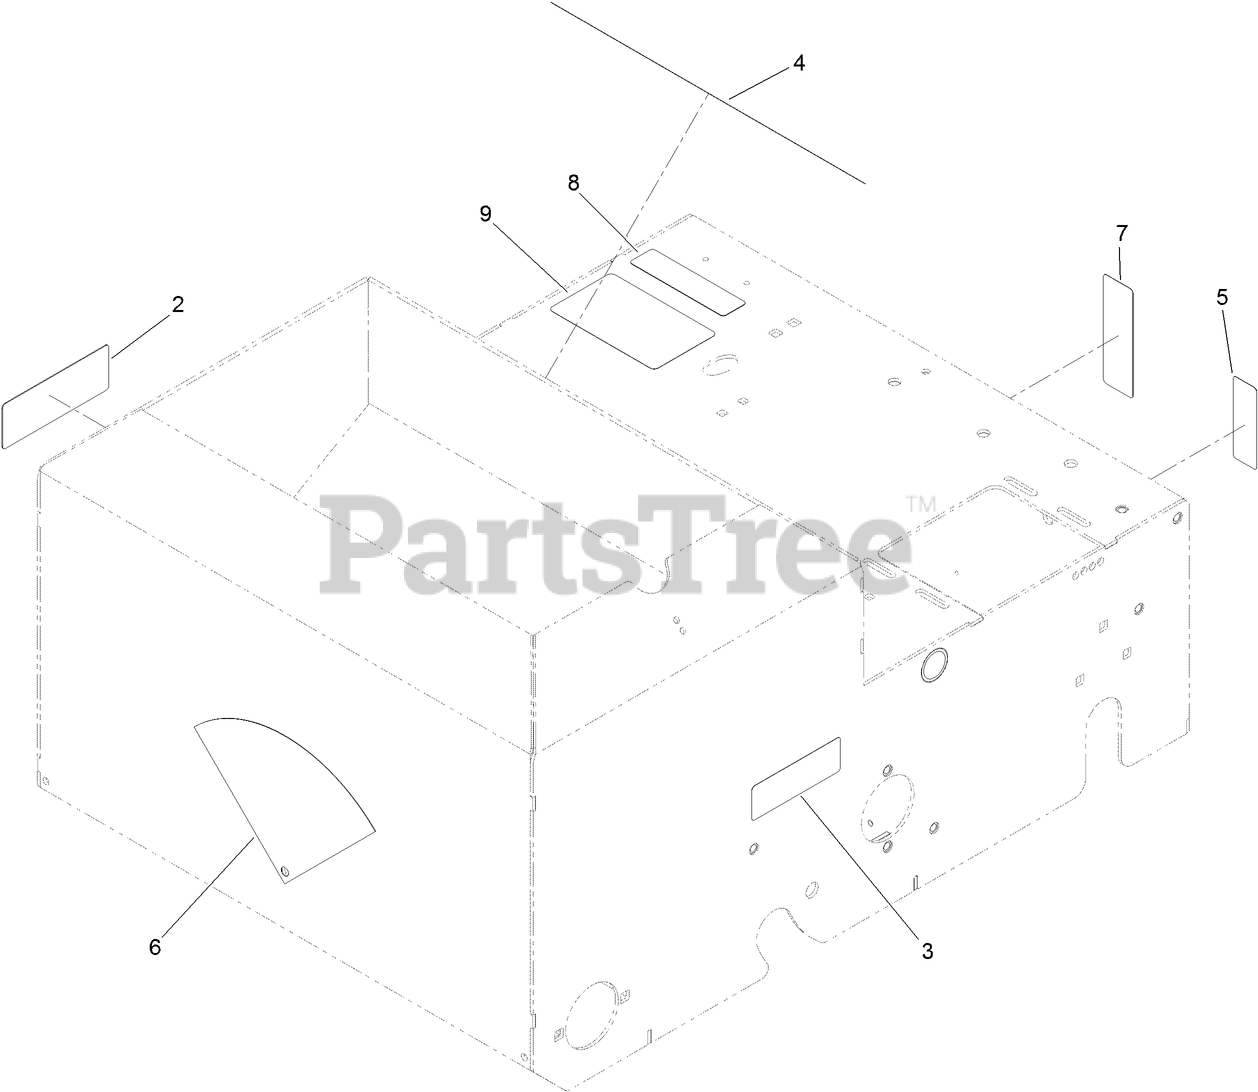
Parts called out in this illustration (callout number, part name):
2	DECAL-DANGER
3	DECAL-WARNING
4	DECAL-WARNING
5	DECAL-BRAKE, PARKING
6	DECAL-FLOW, SEED
7	DECAL-BYPASS
8	DECAL-ARRESTER, SPARK
9	DECAL-AID, SERVICE
